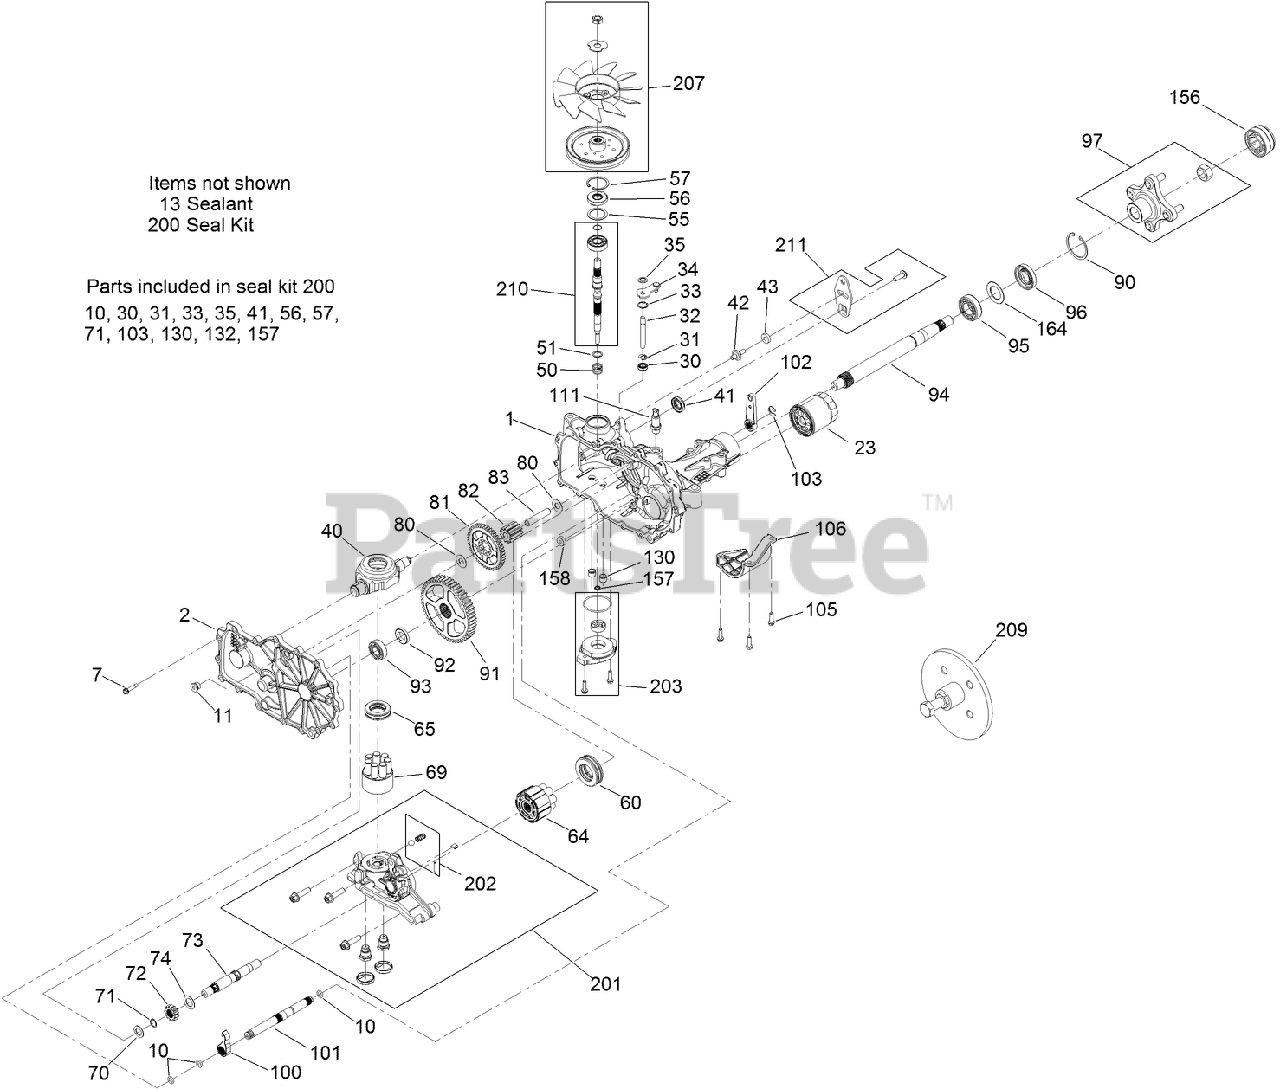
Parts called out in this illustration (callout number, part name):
1	RH MAIN HOUSING KIT
2	RH SIDE COVER KIT
7	SCREW-HHF
10	O-RING
11	PLUG-THREAD, STRAIGHT
23	ELEMENT-OIL FILTER, HYD
30	SEAL-LIP
31	RING-RETAINING, EXTERNAL
32	ROD-BYPASS
33	RING-RETAINING, INTERNAL
34	ARM-BYPASS
35	RING-RETAINING, EXTERNAL
40	SWASHPLATE-TRUNNION
41	SEAL-LIP
43	PUCK-FRICTION
50	SPRING-COMPRESSION
51	WASHER
55	SPACER
56	SEAL-LIP
57	RING-RETAINING
60	Bearing-Thrust
64	MOTOR CYLINDER BLOCK KIT
65	BEARING-THRUST, PLASTIC CAGE
69	7 PISTON BLOCK ASM
70	WASHER-FLAT
71	RING-RETAINING
72	GEAR-13T
73	SHAFT-MOTOR
74	WASHER
80	WASHER
81	GEAR-46T
82	GEAR-11T
83	PIN-JACKSHAFT
90	RING-RETAINING
91	GEAR-54T
92	SPACER
93	BEARING-BALL
94	SHAFT-AXLE
95	BEARING-BALL
96	SEAL-LIP
97	HUB KIT
100	PAWL-BRAKE
101	SHAFT-BRAKE
102	HANDLE-BRAKE
103	RING-RETAINING, EXT
106	GUARD-FILTER, RH
111	ADAPTER-STRAIGHT
130	TUBE-PUSH, O-RING
156	COVER-NUT, AXLE
157	SEAL-GEROTOR
158	MAGNET-RING
164	SPACER
201	CENTER SECTION KIT
202	CHARGE RELIEF KIT
203	CHARGE PUMP KIT
207	FAN AND PULLEY KIT
209	HUB PULLER KIT
210	INPUT SHAFT KIT
211	CONTROL ARM KIT
